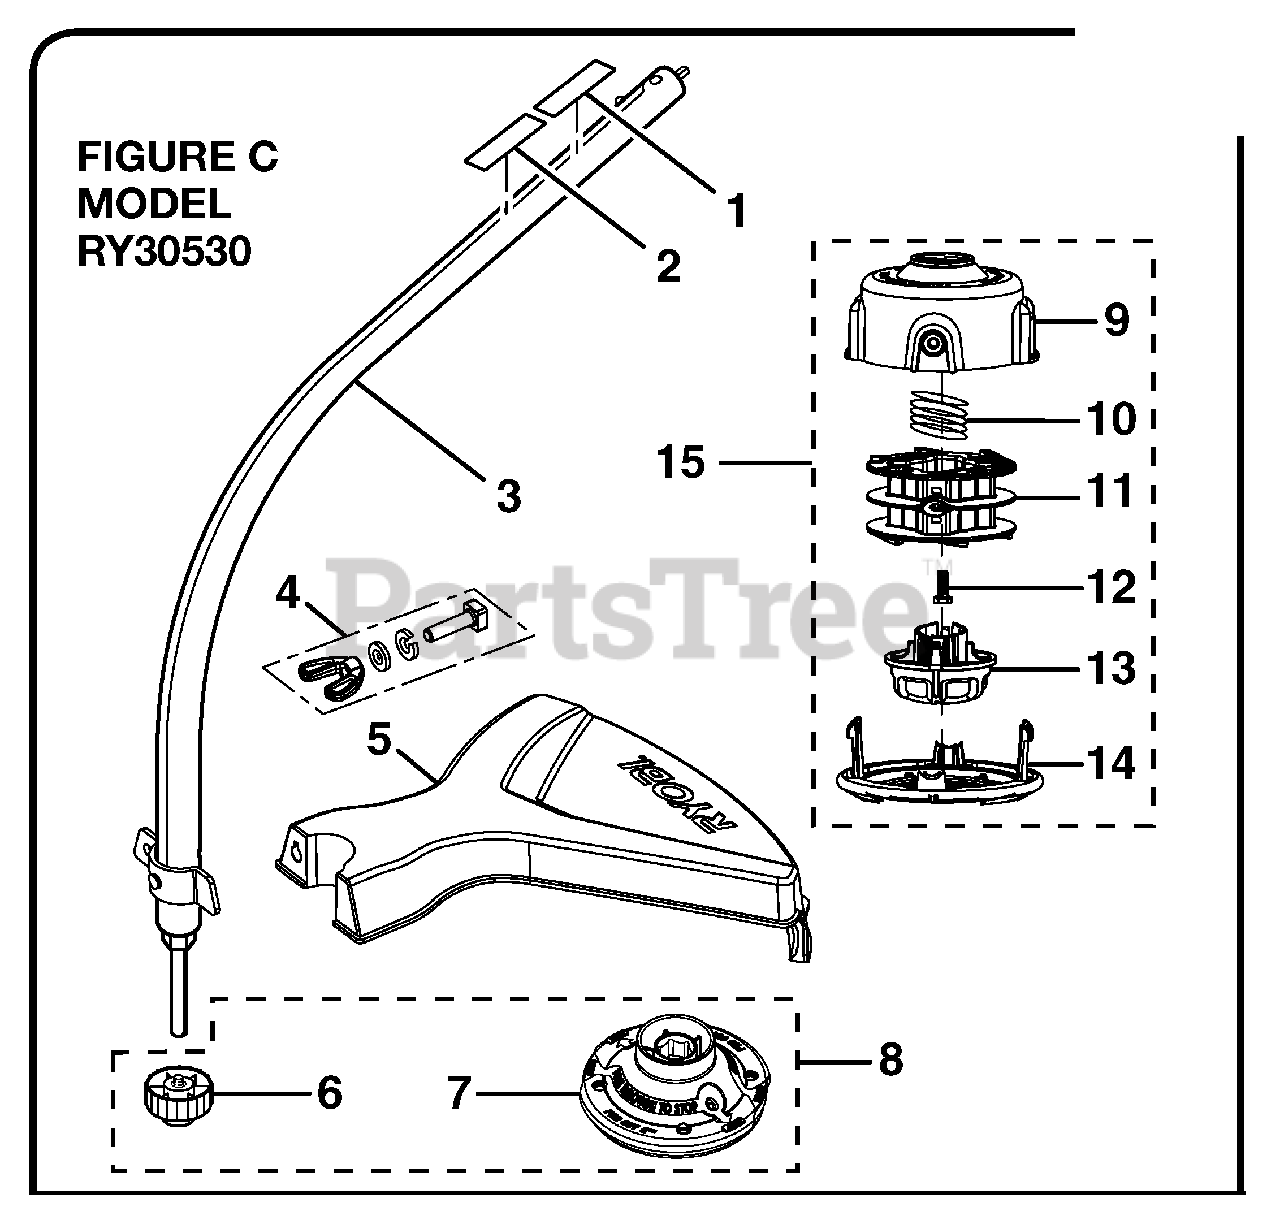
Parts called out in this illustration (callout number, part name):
1	Expand-it Label
2	Warning Decal
3	Curved Shaft Assembly
4	Fastener Kit
5	Grass Deflector
6	Spool Retainer
7	Pro Cut II String Head
8	Pro Cut II String Head Assembly
9	Housing
12	Bolt
15	Reel Easy String Head Assembly
